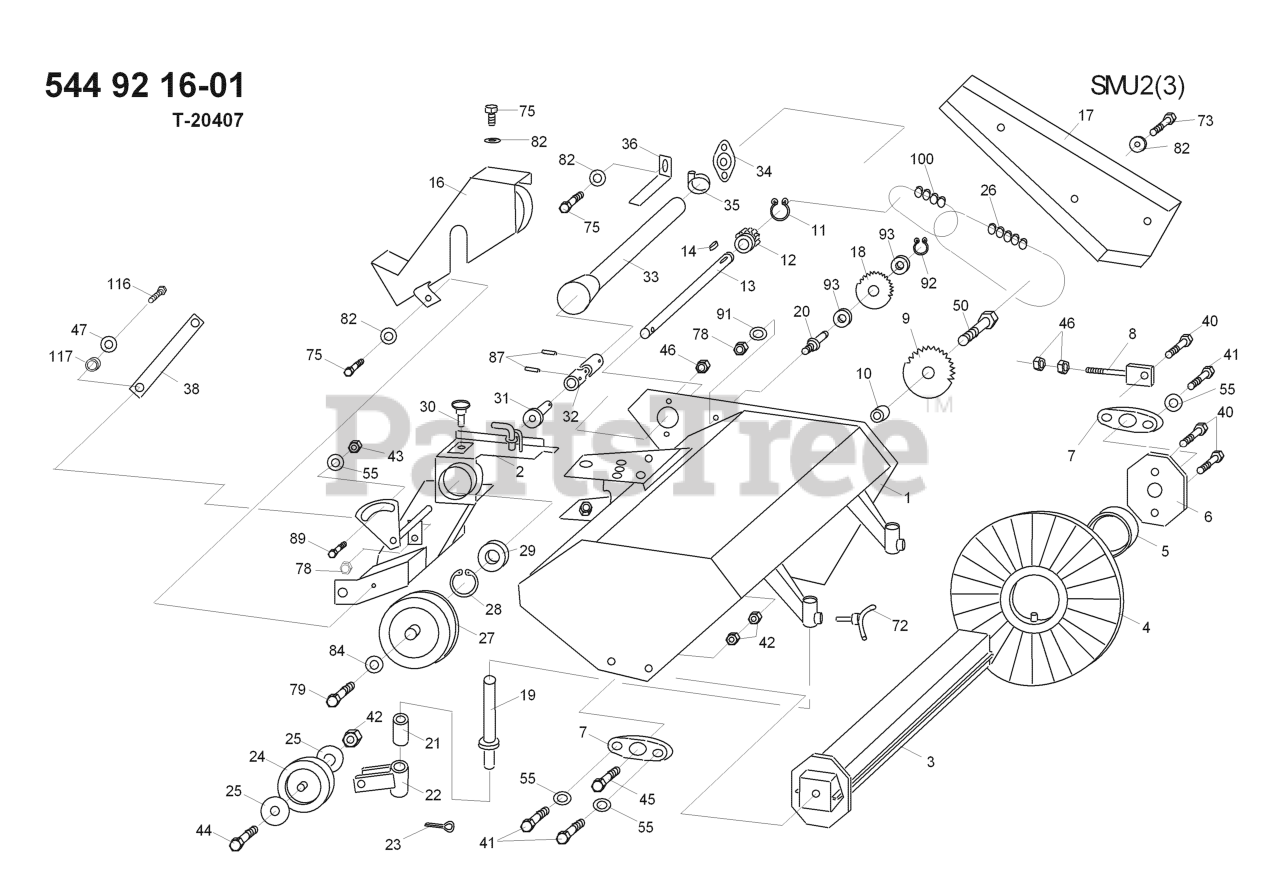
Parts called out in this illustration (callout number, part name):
4	BRUSHSEGMENT
5	WASHER BRUSHSEGMENT
7	BEARING UCFL 204
8	CHAINTIGHTNER
9	CHAINWHEEL
12	CHAINWHEEL
28	RETAINING RING
